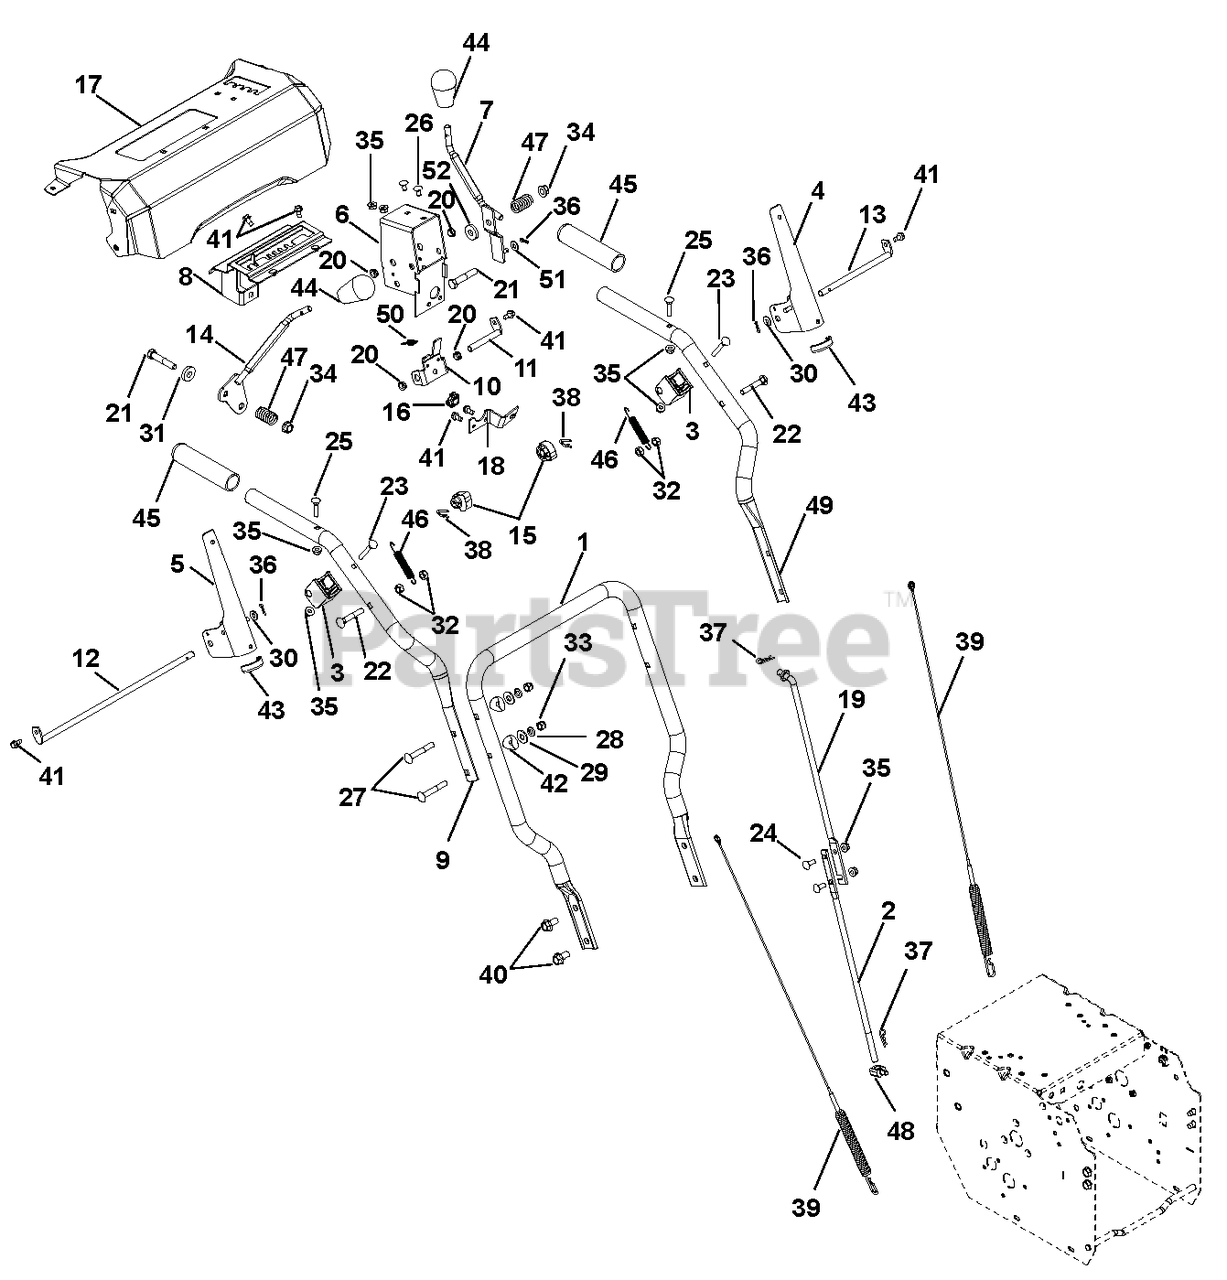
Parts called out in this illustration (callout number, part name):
1	HANDLEBAR, LOWER (COMPACT)
2	ROD, SHIFT - LOWER
3	BLOCK, CLUTCH PADDLE
4	LEVER, CLUTCH-LH
5	LEVER, CLUTCH-RH
6	WELDMENT, BRACKET INTERLOCK
7	WELDMENT, CONTROL LEVER (DEFL)
8	WELDMENT, DETENT PLATE-COMPACT
9	HANDLEBAR, UPPER - RH
10	BRACKET, INTERLOCK ARM
11	ROD, PIVOT - INTERLOCK
12	ROD, PADDLE MOUNT - LONG
13	ROD, PADDLE MOUNT - SHORT
14	LEVER, CONTROL-SHIFT(WELDMENT)
15	CAM, INTERLOCK
16	CRANK BUSHING, NYLON CHUTE BK
17	CTRL PANEL W/DECAL SNO-TEK MAN
17	CTRL PANEL W/DECAL,SNO-TEK,REM
18	ANCHOR, DEFLECTOR CABLE
19	ROD, SHIFT - UPPER
20	BUSHING, POLYLINER-.38 SNAPIN
21	@BLT-HEX .38-16X2.00 GR5 YWZC
22	BLT-RDHDXLSQNK .31-18X2.0 G5YZ
23	BLT-RDHDXLSQNK .25-20X2.0 G5YZ
24	@BLT-RDHDSQNK .25-20X.75 G5YZ
25	BLT-RDHDXLSQNK.25-20X1.25 G5ZC
26	@BLT-RDHDSQNK .25-20X.50 G5YZ
27	@BLT-RDHDSQNK .31-18X2.25 G5YZ
28	WSHR-LK .312X.097 HVY YWZC
29	@WSHR-FL-STL.38X.875X.083 YWZC
30	@WSHR-FL-STL.281X.62X.065 YWZC
31	WSHR-FL-STL .406X1.00X.188 YWZ
32	@NUT-LK-CTR .31-18 YWZC
33	@NUT-LK-NYL .312-18 YWZC
34	@NUT-LK-TOP-FLG .38-16 YWZC
35	@NUT-LK-CTR-FLG .25-20 YWZC
36	PIN-HAIR INT .06X.18X.77
37	PIN-HAIR INT .08X.18X1.18 YWZC
38	PIN, SPRING CLIP
39	CABLE, AUGER & UPPER TRACTION
40	BLT-SERHFWH .38-16X.75 YWZC
41	SCR-TAP .25-20X.50 HWH TR YWZ
42	SPACER, HANDLEBAR
43	EDGING, CLUTCH PADDLE - 2.00"
44	KNOB,SOFT TEARDROP,PUSH-ON BLK
45	HANDLE GRIP
46	SPRING, EXTENSION
47	SG-COMP .125X.781X1.250
48	PIVOT,SHIFT ROD .375-16(TRUNN)
49	HANDLEBAR, UPPER - LH
50	SPRING-EXT .047X.438X1.45
51	BSHG-SLV .265X.500X.219
52	WSHR-FL-STL .380X1.50X.062 YWZ
